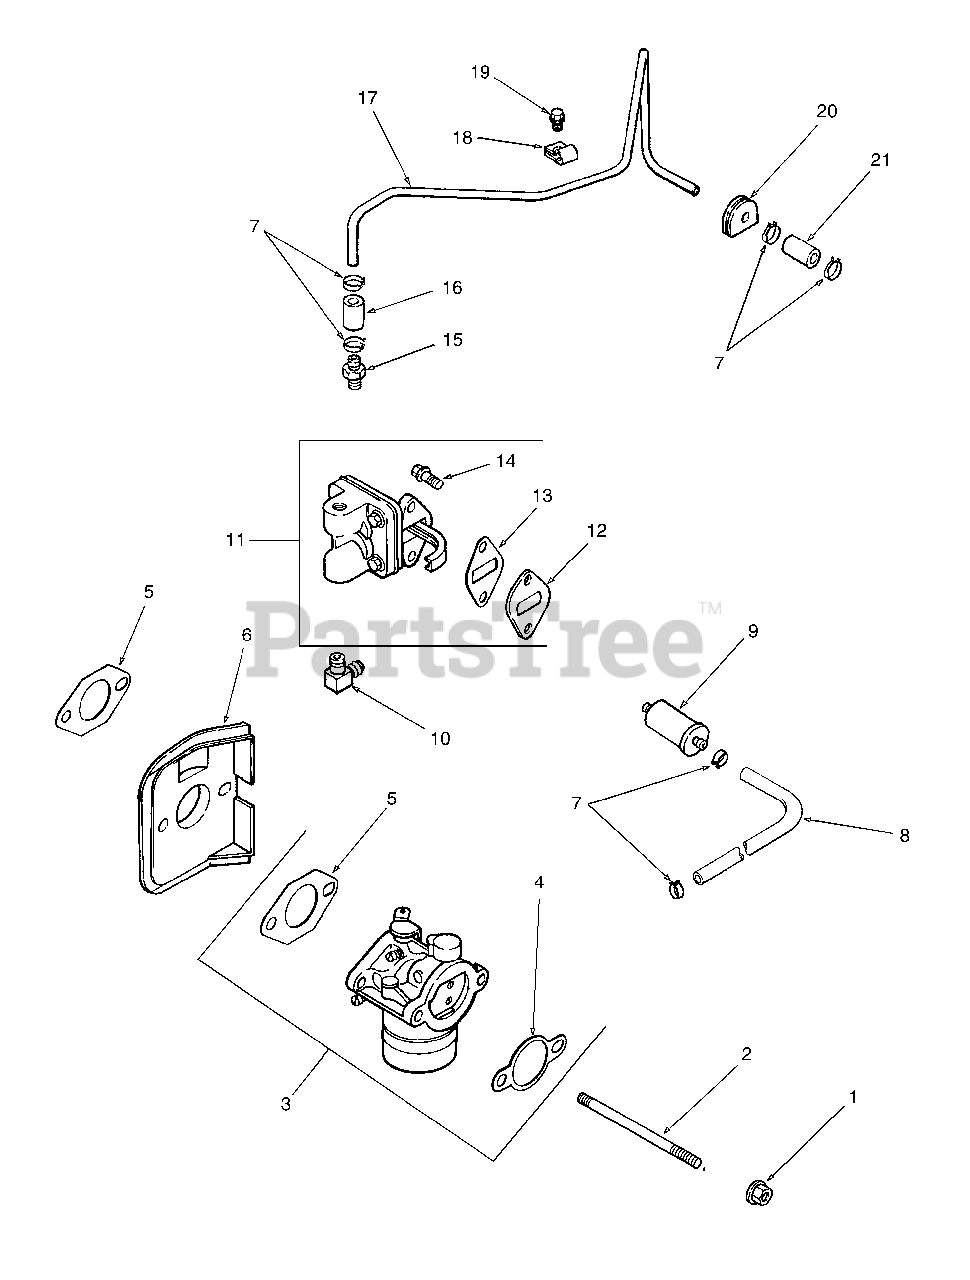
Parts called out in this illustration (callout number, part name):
1	Nut, Hex Flange, M6 x 1.0
2	Stud, M6 x 1.0 x 122
3	Kit, Carburetor w/Gaskets
4	Gasket, Air Cleaner
5	Gasket, Carburetor
6	Deflector, Heat
7	Clamp, Fuel Line
8	Line, Fuel 3"
9	Filter, Fuel
10	Connector, 90° Hose
11	Kit, Fuel Pump
12	Spacer, Fuel Pump
13	Gasket, Fuel Pump
14	Screw, Hex Flange, M6 x 1.0 x 20
15	Connector, Straight Hose
16	Line, Fuel 2-1/2"
18	Clamp, Fuel Line
19	Screw, Hex Flange, M5 x 0.8 x 10
21	Line, Fuel 1-1/4"
